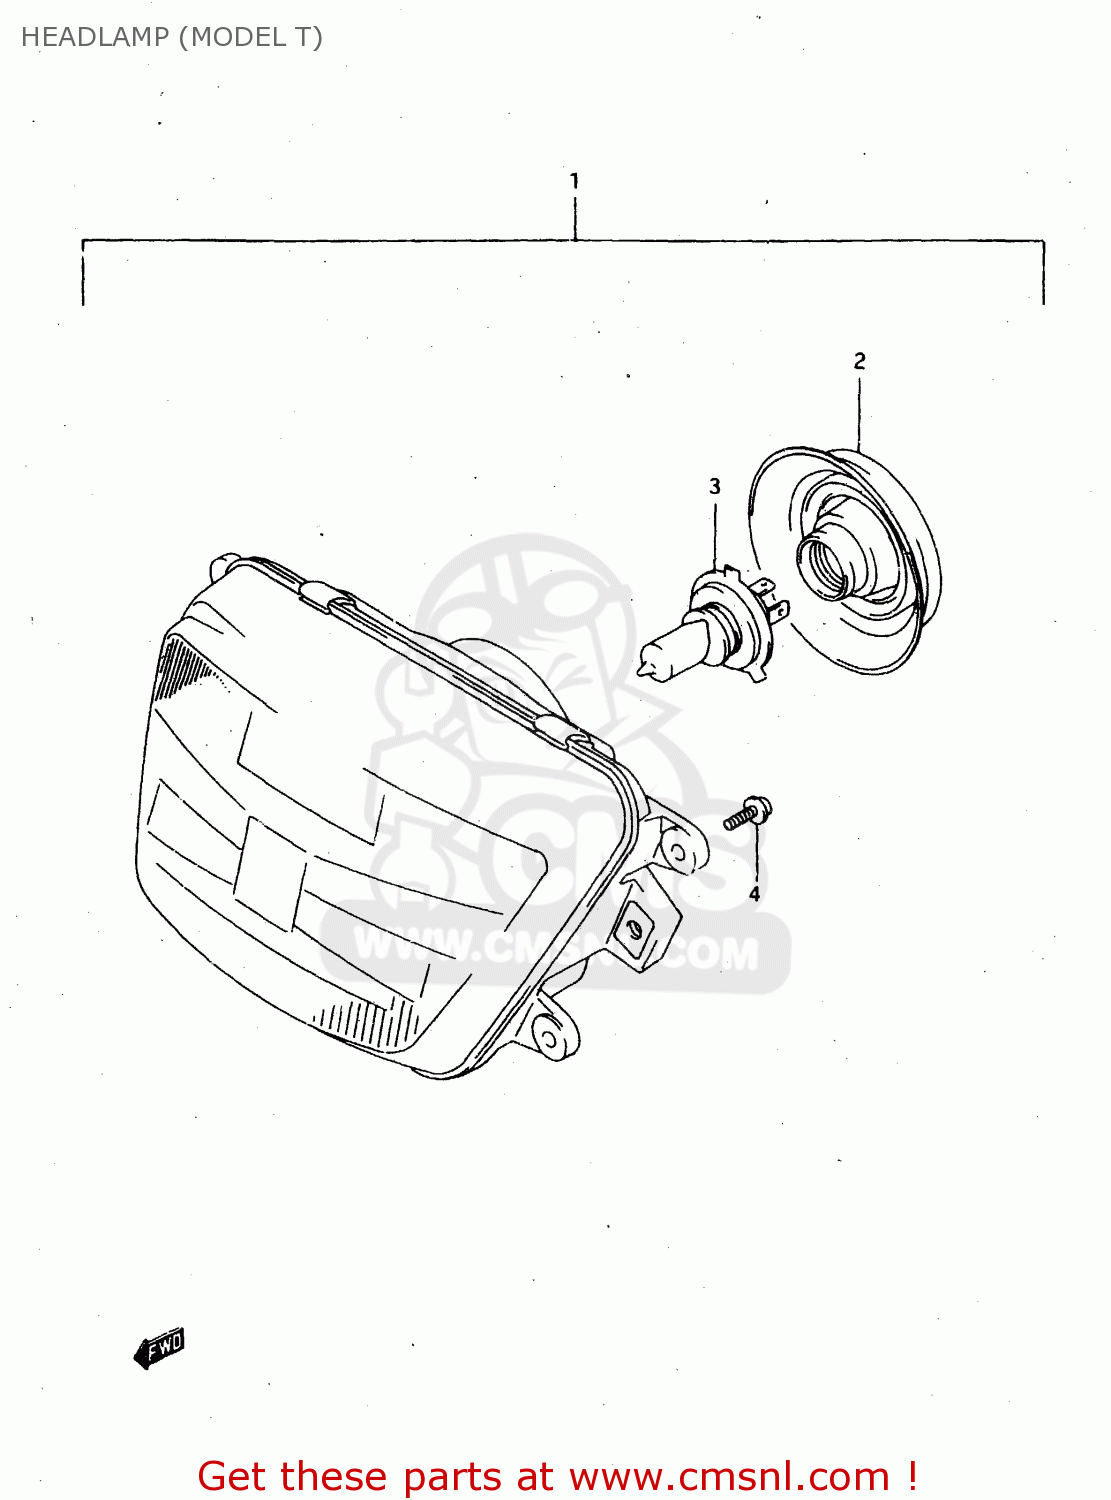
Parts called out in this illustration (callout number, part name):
1	HEADLAMP ASSEMBLY
2	COVER,SOCKET
3	BULB(12V60/55W,H4)
4	SCREW
